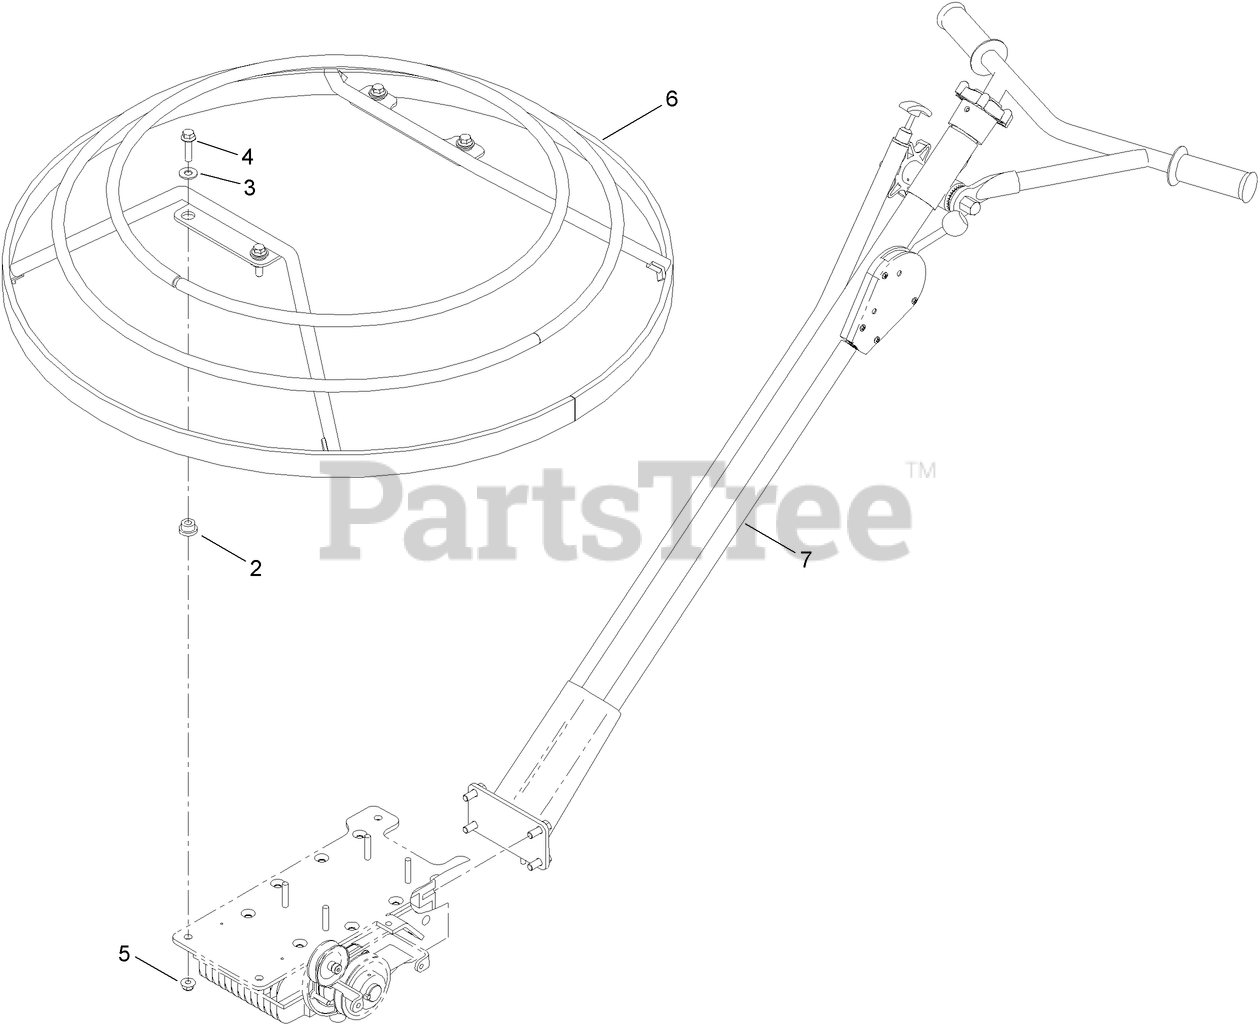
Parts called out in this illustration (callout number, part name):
2	MOUNT-SHOCK
3	WASHER-FLAT
4	SCREW-HHF
5	NUT-HF, NI
6	GUARD-STATIONARY
7	HANDLE-STANDARD
